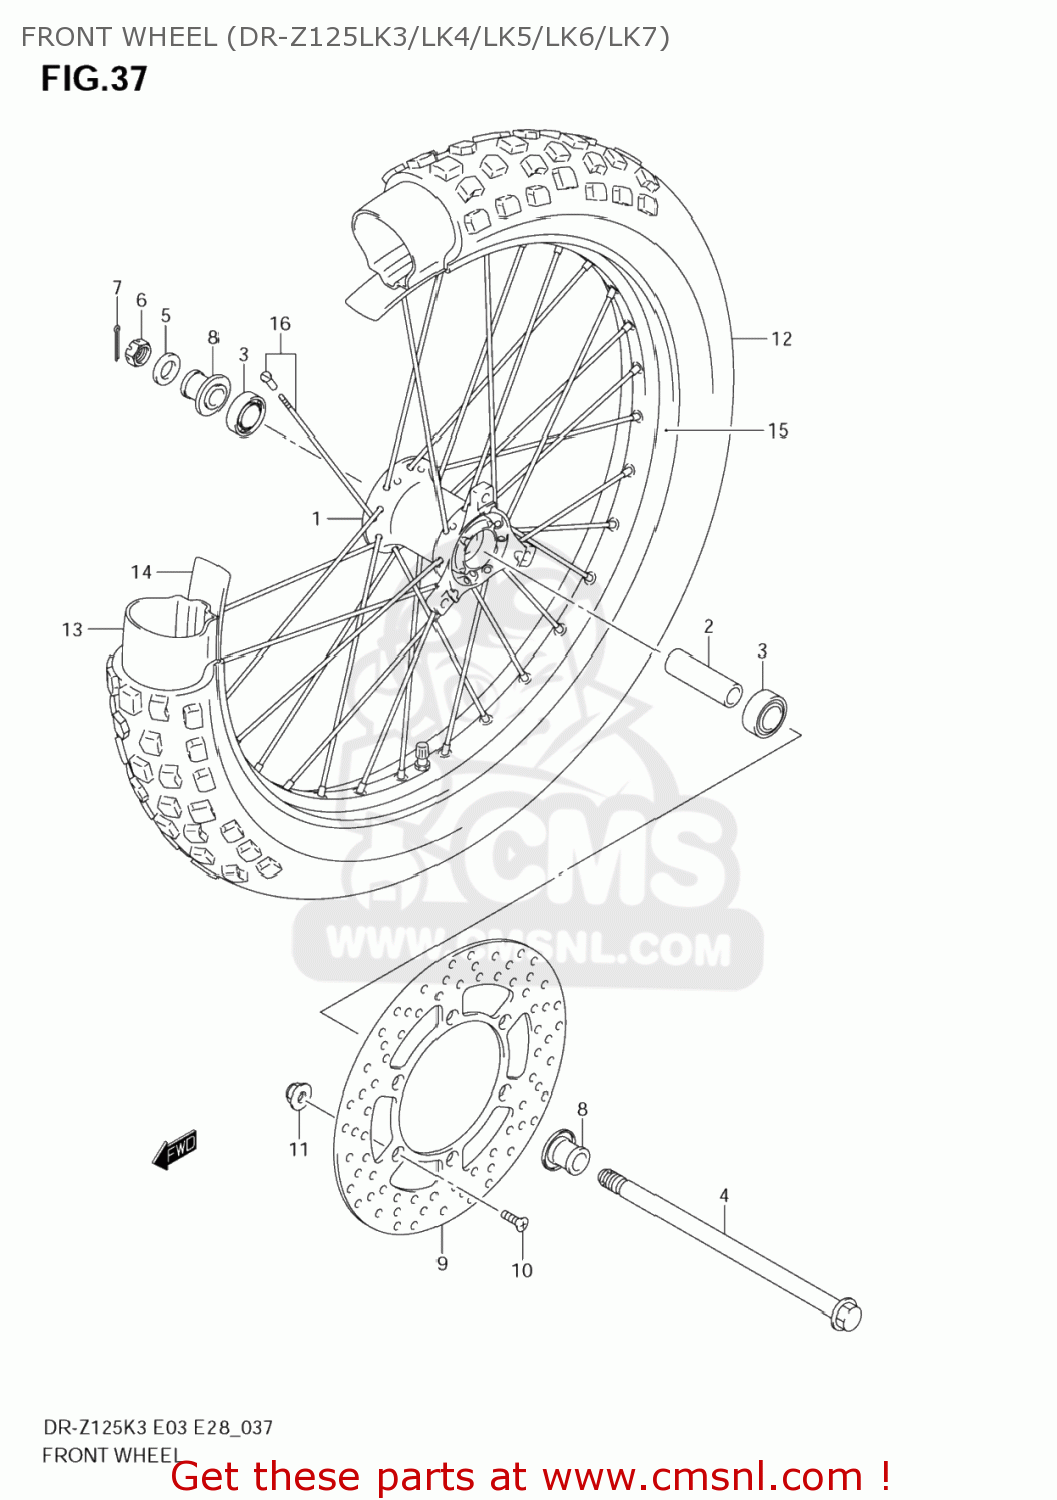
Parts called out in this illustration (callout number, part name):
1	HUB,FR WHEEL
2	SPACER,FR HUB BEARING
3	BEARING (12X32X10)
4	AXLE,FR
5	WASHER(12.5X24X3.2)
6	NUT,M12X1.25X1
7	PIN 20X20
8	SPACER,FR AXLE
9	DISC,FR BRAKE
10	SCREW(6X22)
11	NUT
12	TIRE,FR
13	TUBE ASSY,WHEEL INNER
14	PROTECTOR,WHL INR TUBE
15	RIM,FR WHEEL(19X1.40)
16	SPOKE SET,FR WHEEL
